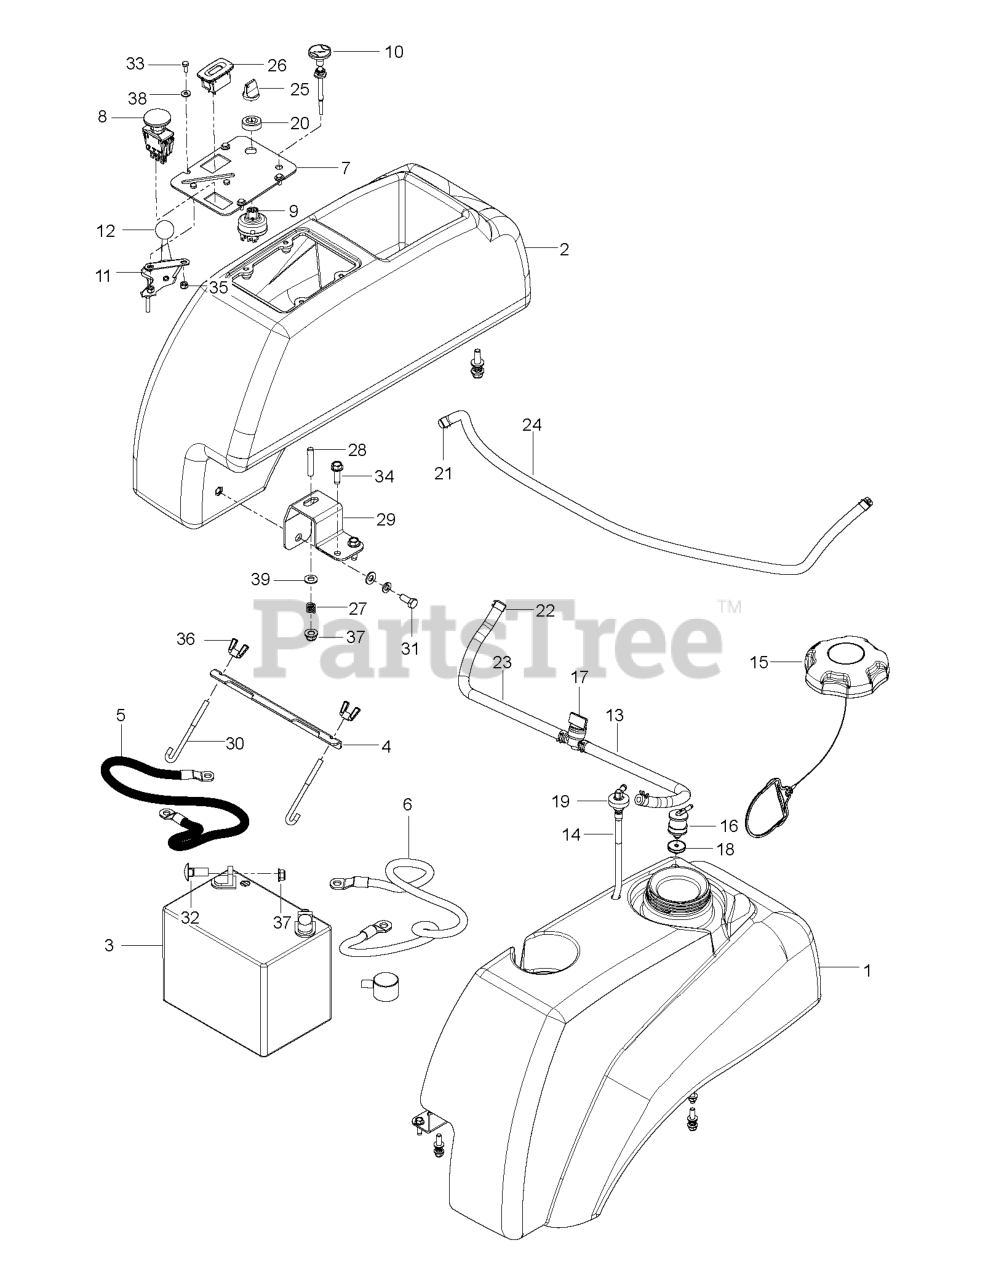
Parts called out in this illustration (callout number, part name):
1	FUEL.TANK.ASSY.LH.MZ.BLK.17
2	CONSOLE, RT-BLK
3	BATTERY, 12 V 330 AMP
4	BRACKET.BATTERY.MOUNT.PLATED
5	CABLE.GROUND.BATT.MZ.BLACK.39"
6	CABLE.BATT.SOLENOID.MZ.RED.25"
7	PLATE.CONSOLE.BLACK
8	RP SWITCH.PTO.TERMINAL.STD.RED
9	SWITCH, IGNITION, INDAK
10	CABLE, CHOKE, 38
11	THROTTLE CABLE
12	KNOB.ROUND.BALL.BLACK
13	FUEL.HOSE.SHUT.OFF.ASM.10".10"
14	FITTING, FUEL
15	CAP, FUEL
16	VALVE.FUEL.CHECK
17	FUEL VALVE
18	GROMMET, CHECK VALVE
19	RUBBER GROMMET
20	CAP IGNITION NUT
21	CLAMP, HOSE
22	HOSE CLAMP
23	HOSE.1/4".LOW.PERM.FUEL.LN.10"
24	HOSE.3/16".VAPOR.LINE.27"LGTH
25	KEY, IGNITION
26	GUAGE.SRVCMNDR.HRMTR.
28	STUD, 5/16C
29	SUPPORT.PNT.TANK.FRONT.STAMPED
30	HOOK, "J"
31	HCS 5/16C X 3/4
32	BOLT 5/16C X 3/4" CARRIAGE
33	HCS #10-24 X 1/2
34	SCREW
35	NUT 10-24 NYLOC
36	WING NUT 1/4
37	5/16-18 NYLOC FLANGE NUT
38	WASHER
39	WASHER
